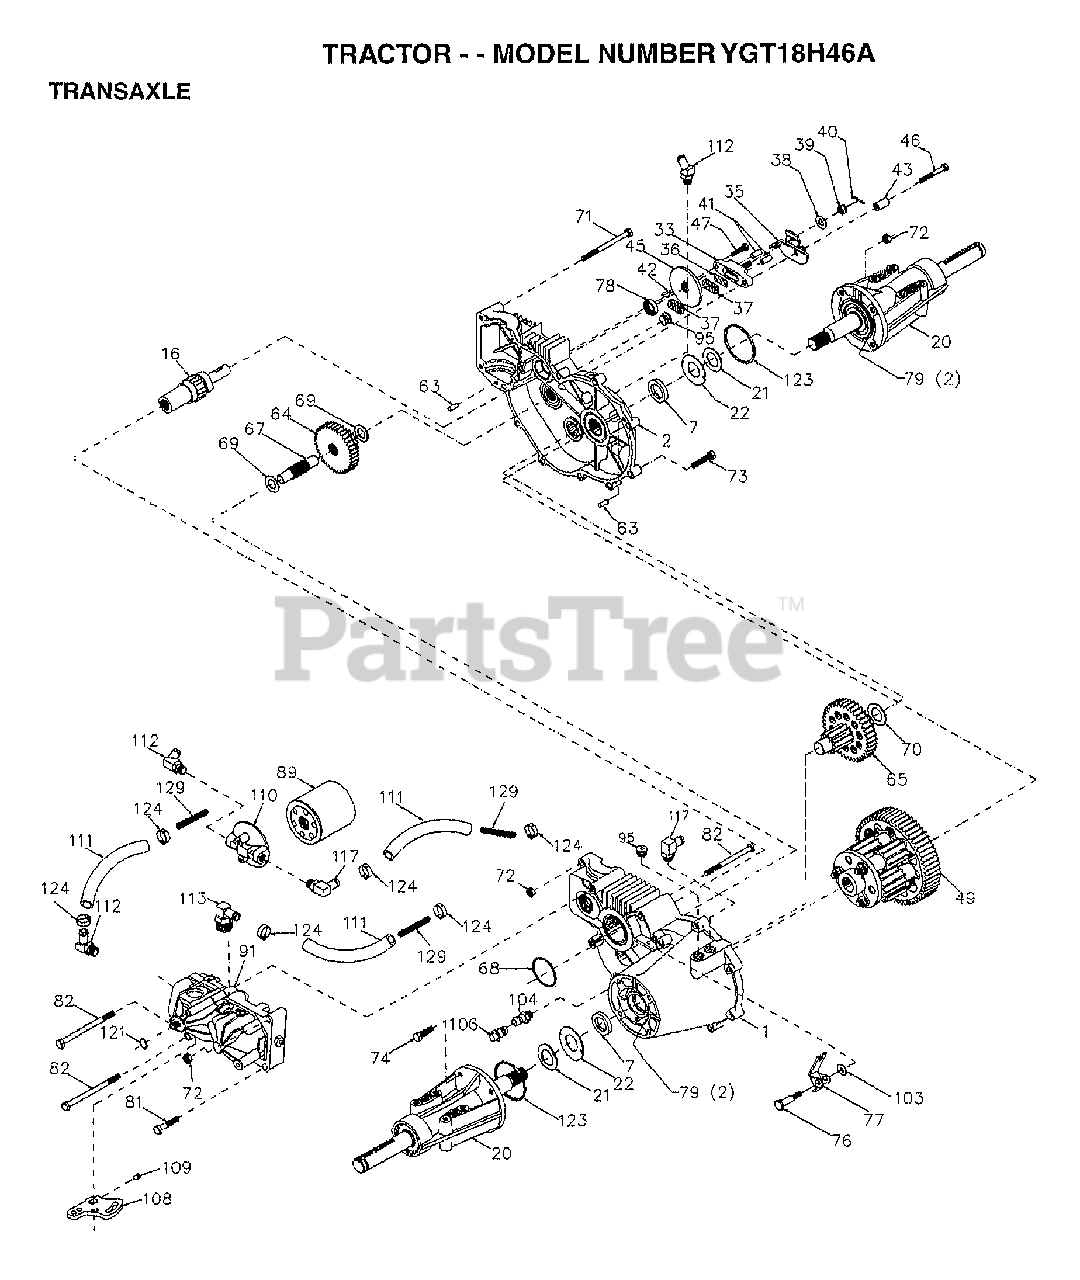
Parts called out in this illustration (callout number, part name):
1	HOUSING LH 70086
2	HOUSING RH 70088
7	SEAL.OIL.44782.HY
16	SHAFT BRAKE 62877
20	AXLE MTG 70087
21	WASHER 44805
22	WASHER 44806
33	YOKE.BRAKE.62589
35	ARM BRAKE 50214
36	PUCK PLATE 44134
37	PUCK BRAKE 44132
38	WASHER HYD 44130
41	PIN BRAKE 44127
42	KEY HI PRO 44143
43	SPACER 50259
45	DISC BRAKE 44090
46	BOLT 1/4-20 44276
47	BOLT 1/4-20 44433
49	DIFFRENTIAL.70251
63	PIN DOWL 44757
64	GEAR.14-38.44776
65	PINION DRIV 70051
67	SHAFT-44779
68	O RING 44781
69	WASHER 44795
70	WASHER 44794
71	BOLT 5/16 44827
72	LOCKNUT.43064
73	BOLT 5/16 44841
74	SCREW 5/16 45089
76	BOLT SHOULD 44785
77	ARM FREEWHL 44786
78	SEAL.OIL.44761
81	BOLT 5/16 43084
82	BOLT 5/16 44820
89	FILTER SPIN 50037
91	PUMP.BDU-10L-122
95	PLUG.9005110-5600
96	FITTING.SAE.50257
103	WASHER.50169
104	CAP.VENT.70109
106	O-RING.ASM.70110
108	ARM.CONTROL.45007
109	SCREW.SET.50018.
110	FILTER.HEAD.50207
111	HOSE.50632
112	FITTING.SAE.50604
113	FITTING.SAE.50592
117	FITTING.SAE.50589
123	O-RING.50405
124	CLAMP.50590
129	SPRING.LONG.50667
